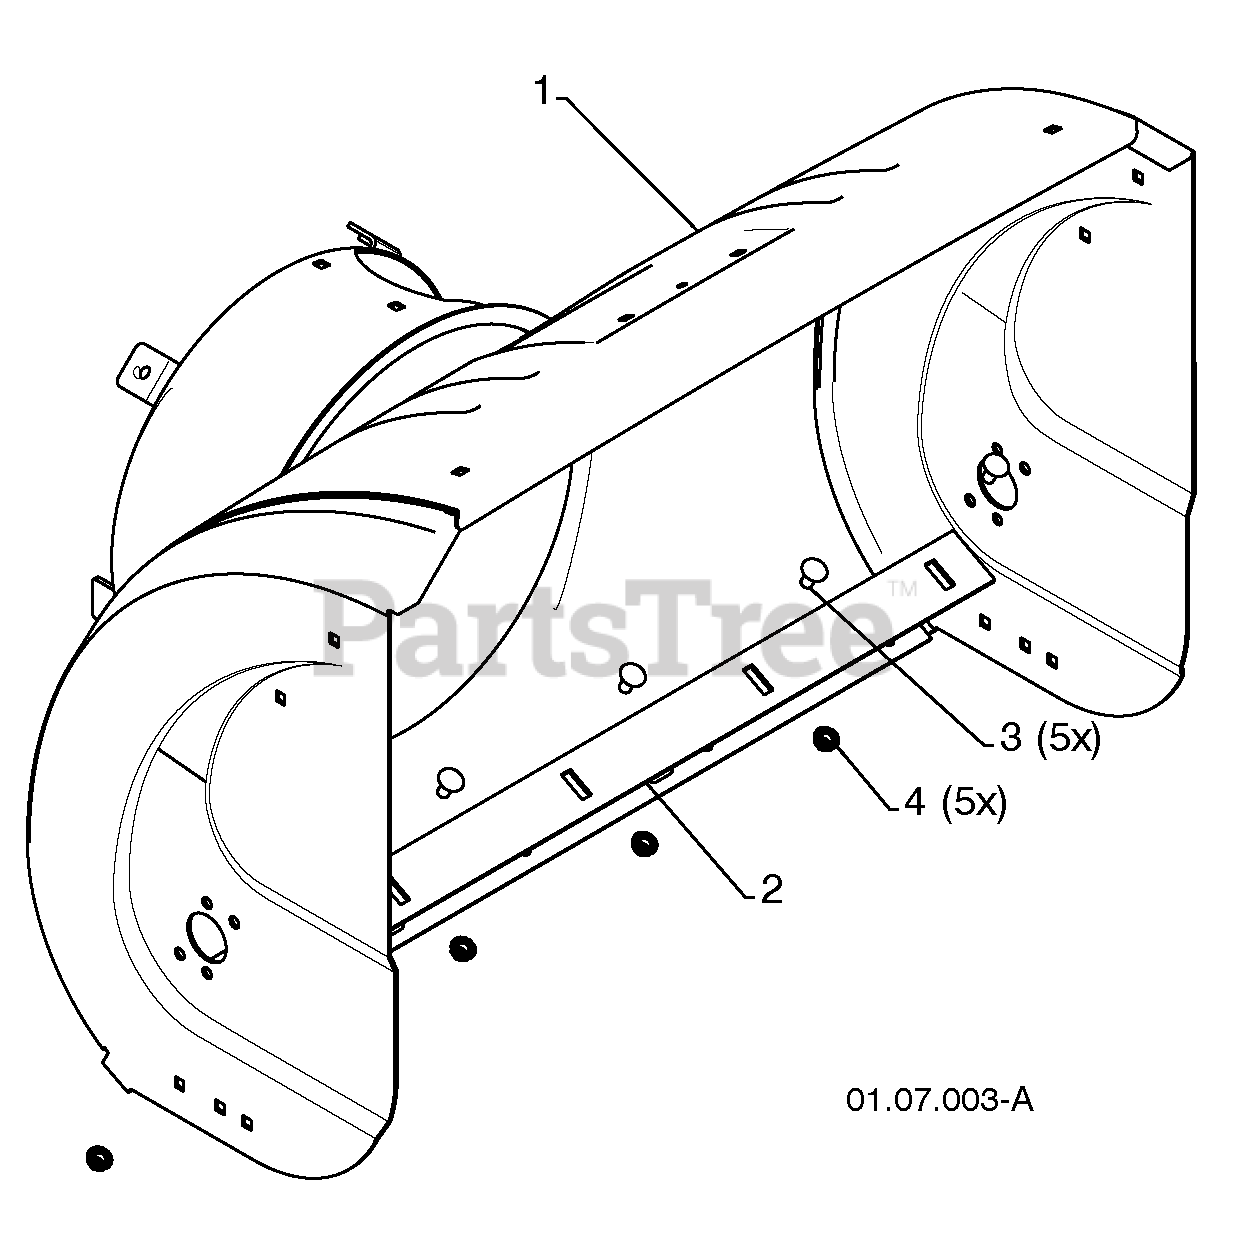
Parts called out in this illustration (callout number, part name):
1	AUGER HOUSING
2	SCRAPPER BAR
3	CARRIAGE BOLT 5/16-18 X .625
4	NUT 5/16-18
